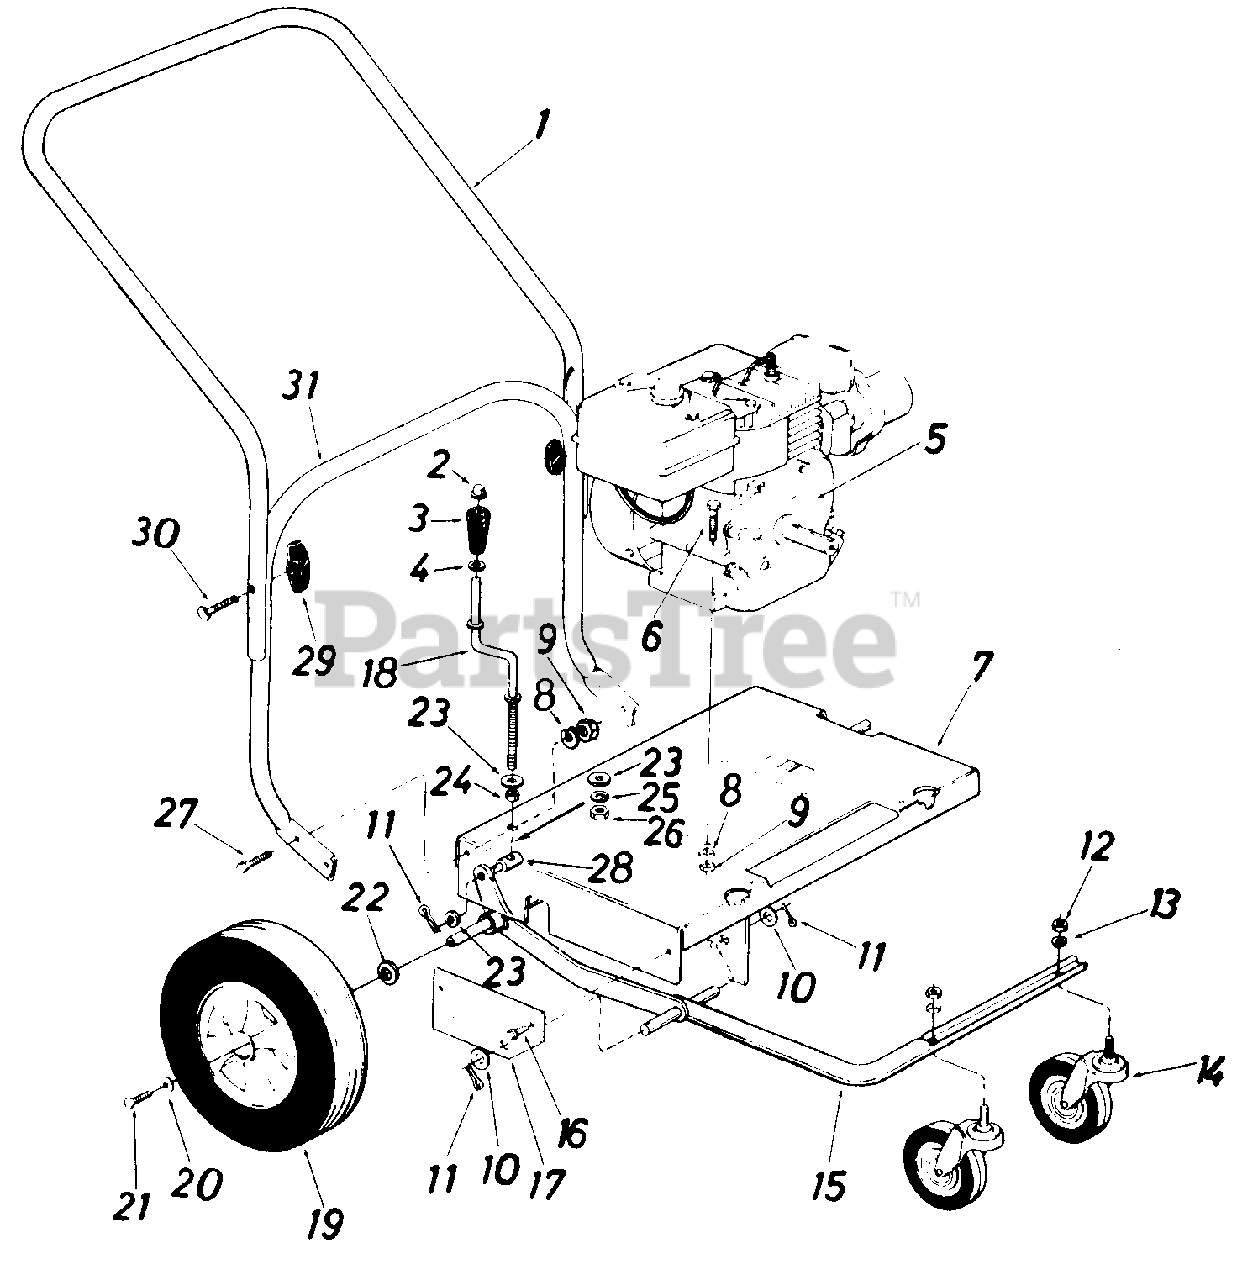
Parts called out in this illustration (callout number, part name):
1	Upper Handle
2	Push Nut 3/8" Rod
3	Crank Knob
4	Fl.-Wash. .385" I.D. x .62" O.D.
5	Sq. Key 1/4" x 2.0" Lg.
6	Hex Bolt 5/16-18 x 1.50" Lg.
7	Engine Mounting Frame Ass'y.
8	L.-Wash . 5/16 " I.D.
9	Hex Nut 5/16-18 Thd.
10	Fl.-Wash. .63" I.D. x 1.25" 0. D.
11	Cotter Pin 1/8" Dia. x 1.0" Lg.
12	Hex Nut 1 /2-1 3 Thd.
13	L.-Wash . 1/2 " I . D.
14	Swivel Caster Wheel 5" Dia. x 1.25"
19	Wheel Ass y. Comp. 12" x 3" (Plastic)
20	Fl.-Wash. 34" 1 .D. x .87 " 0. D.
21	Hex Locking BoIt 5/16-24 x.62" Lg.
22	Fl.-Wash.
23	Fl.-Wash. .38 " I.D. x .57 " O.D.
24	Spacer .382" I.D. x .50" O.D. x .180" Lg.
25	L.-Wash. 3/8" I.D.
26	Hex Nut 3/8-16 Thd.
27	Hex Bolt 5/16-18 x .75" Lg.
28	Ferrule
29	hand Knob
30	Carriage Bolt 5/16-18 x 2.0" Lg.
31	Lower Handle
